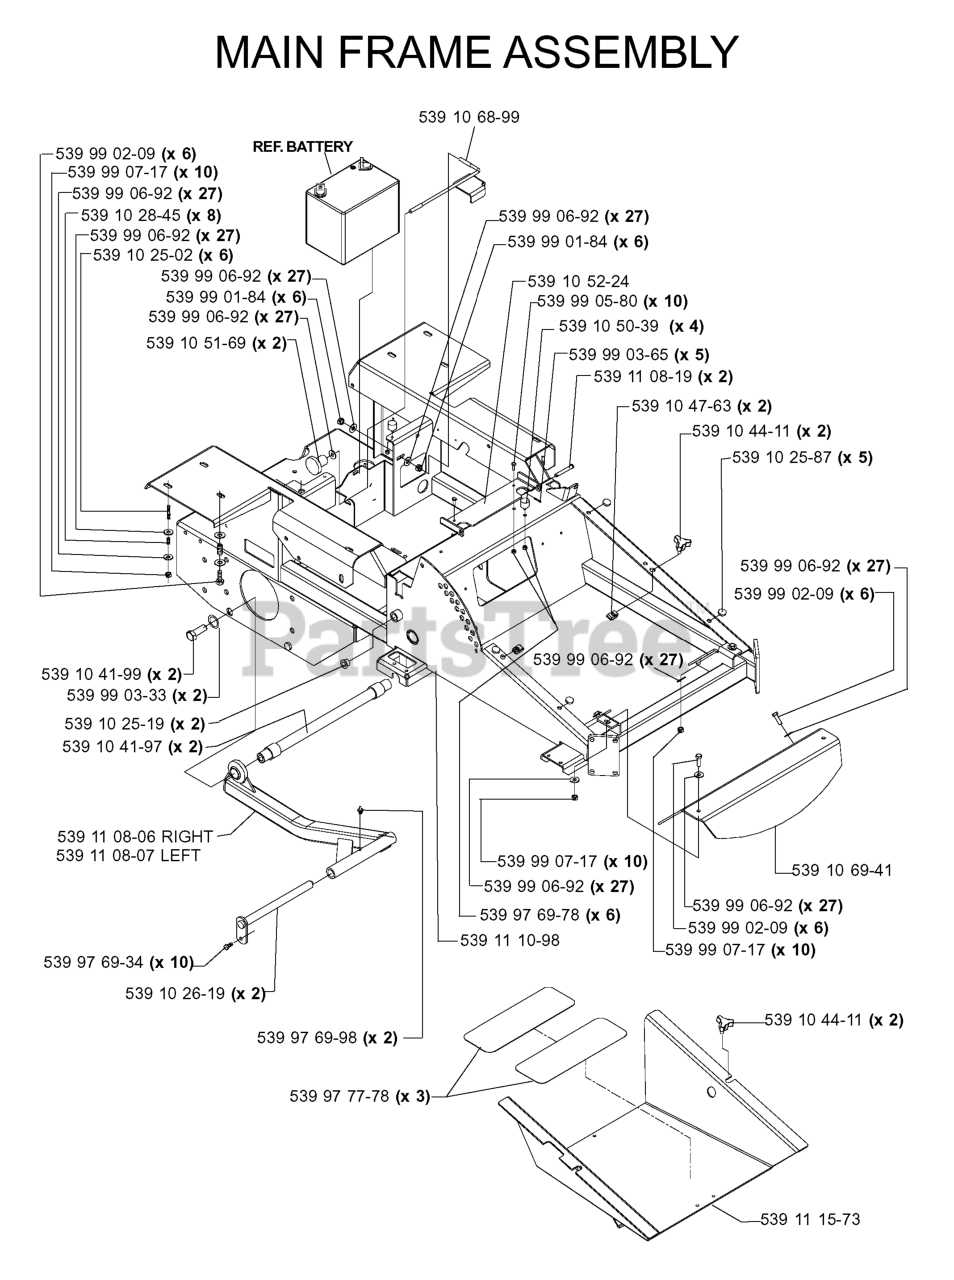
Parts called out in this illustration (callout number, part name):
1	SEAT.ASM.SUSPENSION.TRACK
2	PAN, SEAT, BLACK
3	SEAT SWITCH
4	SEAT BELT, RETRACTABLE
5	ROD, SEAT
6	BRACKET.PNT.LATCH.SEAT.BUMPER
7	SPRING, TORSION
8	BUMPER, RUBBER
9	NUT 3/8 PALNUT RTNG BLK PHOS
10	RP BLT 5/16-18 X 1 THRD FORM D
11	BOLT, SHOULDER 3/8 X 1.25
12	HHFS 3/8-16 X 1.25 GD 5
13	NUT 3/8-16 HEX FLG NYLOC ZD
14	5/16-18 NYLOC FLANGE NUT
